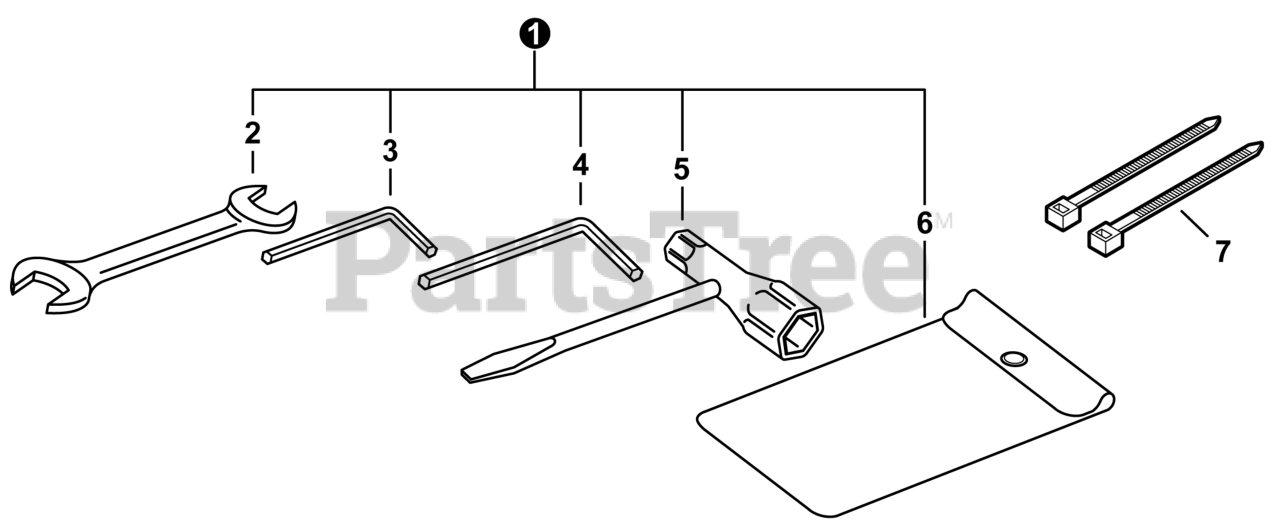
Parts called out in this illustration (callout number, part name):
1	TOOL KIT, SERVICE
2	SPANNER 8×10
3	WRENCH, ALLEN 4 MM
4	WRENCH, ALLEN 5 MM
5	T-WRENCH 17×19 L200
6	BAG, TOOL
7	TIE, CABLE
